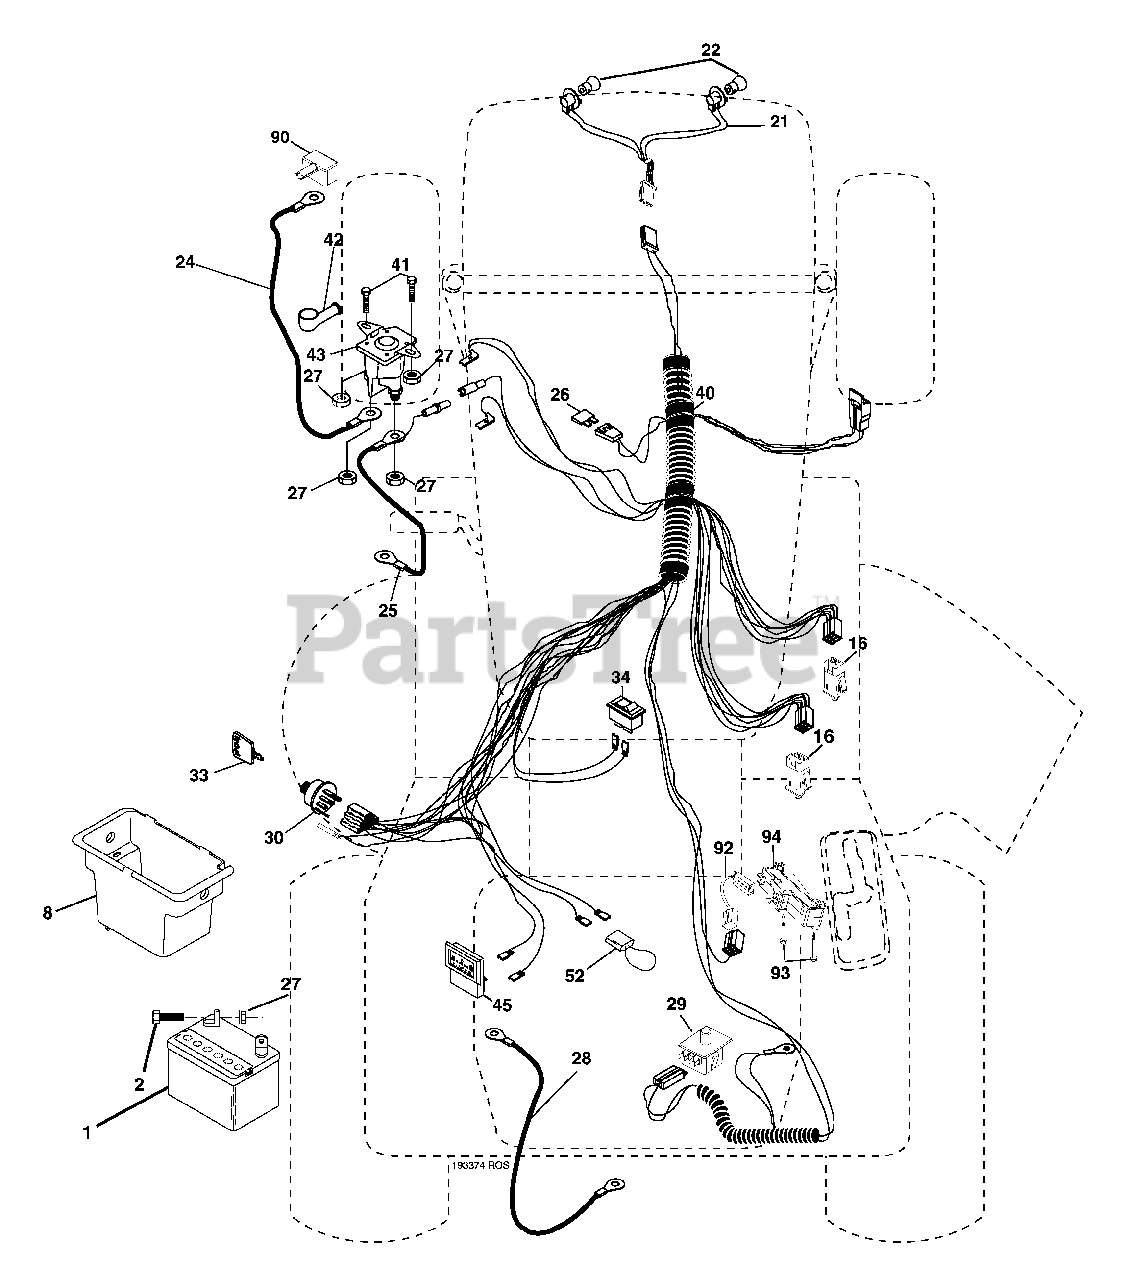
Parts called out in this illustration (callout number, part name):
1	Battery 12 Volt 25 Amp
2	Bolt Hex Hd 1/4-20 unc x 3/4
8	Box Battery
16	Switch Interlock Push -In
21	Harness Asm Light W/4152J
22	Bulb Light #1156
24	Cable Battery 6 Ga. 11" red
25	Cable Battery 6 Ga. w/16 wire,red
26	Fuse 20 AMP
27	Nut Keps Hex 1/4-20 unc
28	Cable Ground 6 Ga. 12" black
29	Switch Seat
30	Switch Ign
33	Key Ign
34	Switch Light/Reset
40	Harness Ign
41	Bolt Blk Fin Hex 1/4-20 x 1/2
42	Cover Terminal Red
43	Solenoid
45	Ammeter
52	Protection Wire Loop
90	Cover Terminal
92	Harness Pigtail
93	Screw Plastite 10-14 x 2.0
94	Module Reverse
